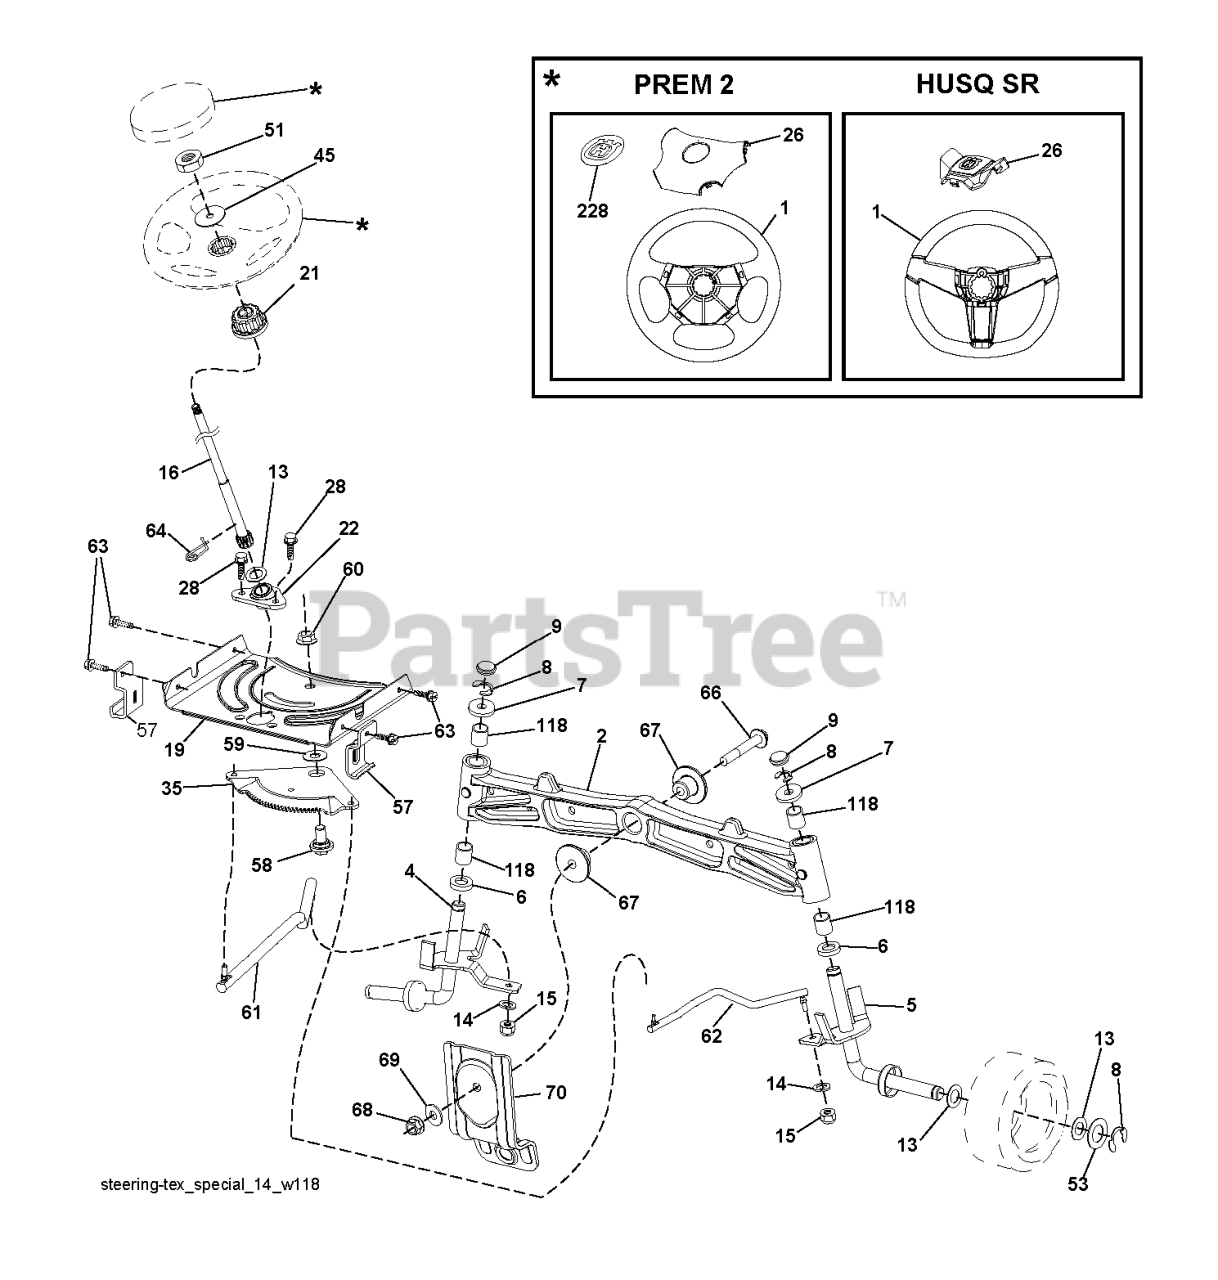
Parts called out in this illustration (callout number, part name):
1	RP WHEEL.STEER.HUSQ.PREM.OVMLD
2	AXLE.SVC.ASM CAST IRON.TEX
4	SPINDLE.WELDED.LH.16"TEX
5	SPINDLE.WELDED.RH.16"TEX
6	THRUST WASHER
9	CAP.SPINDLE.BLACK
14	WASHER, LOCK 3/8
15	NUT CROWNLOCK 3/8-24
16	SHAFT.STEER.STEALTH.DD
19	PLATE.STEER.DDL.NLT/NG
21	ADAPTER, WHEEL STNG..
22	BUSHING.ASM.STEERING.A
26	RP INSERT.CAP.WHL.STRG.HUSQ.
28	SCREW, 3/8-16X3/4
35	GEAR.SECTOR.PLATE.DDL.
45	WASHER 9/16"ID, 2 3/8"OD
51	NUT.HEX.1/2-20
53	WASHER.HARDENED
57	BRKT.UPSTOP.GT/LT.TEX
58	BOLT.SHOULDER.SECTOR.P
59	WASHER.THURST.SECTOR.S
60	NUT FLANGE LOCK 5/8-11
61	DRAGLINK.LH.BALLSTUD.D
62	DRAGLINK.RH.BALLSTUD.D
63	SCREW
64	RETAINER.CLIP.SPRING.S
66	BOLT HEX FGHD 7/16-14 X 3 SERR
67	BUSHING.PM.FRONT AXLE
68	NUT.LOCK.FLANGE.7/16
69	WASHER.1.5X.505X.118
70	BRKT.DECK.SUSPENSION.F
79	DECAL.WHEEL.STRG.LGN.H
118	BUSHING, AXLE CAST
